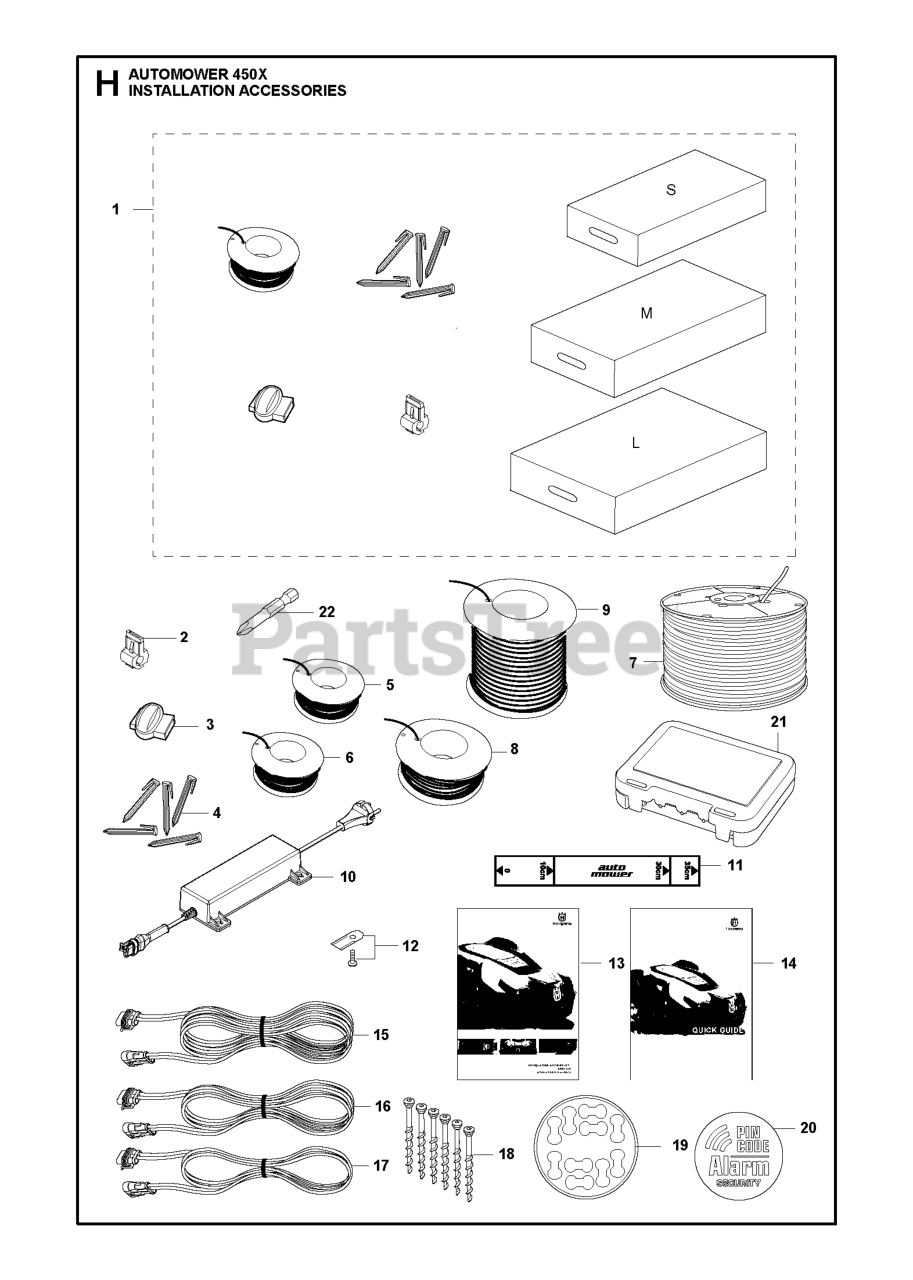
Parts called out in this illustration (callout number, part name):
1	LARGE AUTOMOWER INSTALL KIT
1	MED AUTOMOWER INSTALL KIT
1	SMALL AUTOMOWER INSTALL KIT
2	CONNECTOR 5 PCS, BLISTER
2	BRAKER
2	CONNECTOR 100 PCS
3	SPLICE KIT
3	COUPLER SPLICER, 5 PCS,
3	COUPLER SPLICER, 100 PCS
4	STAPLE 100 PCS, BLISTER
4	STAPLE 100 PCS
5	WIRE BOUNDARY 150M
5	WIRE 50M STANDARD Ø2.7MM,BLIST
5	WIRE 150M, BLISTER
6	WIRE 250M
8	WIRE 500M
9	WIRE (800M)
10	POWER UNIT POWER SUPPLY UNIT 7
11	RULER / CENTIMETERS
12	HUS BLADE SET 300 PCS
12	HUS BLADE SET 45 PCS
12	HUS BLADE SET 9 PCS
15	CABLE LOW VOLTAGE CABLE P2 5-7
16	CABLE LOW VOLTAGE CABLE P2 5-7
17	CABLE LOW VOLTAGE CABLE P2 5-7
18	SCREW KIT CS
18	SCREW 3 PCS, BLISTER PACK
19	STICKER CABLE MARKERS KIT 10PC
20	LABEL SECURITY
21	CONNECTOR PROTECTION BOX
22	WRENCH BITS CHANGING ROBOTIC B
